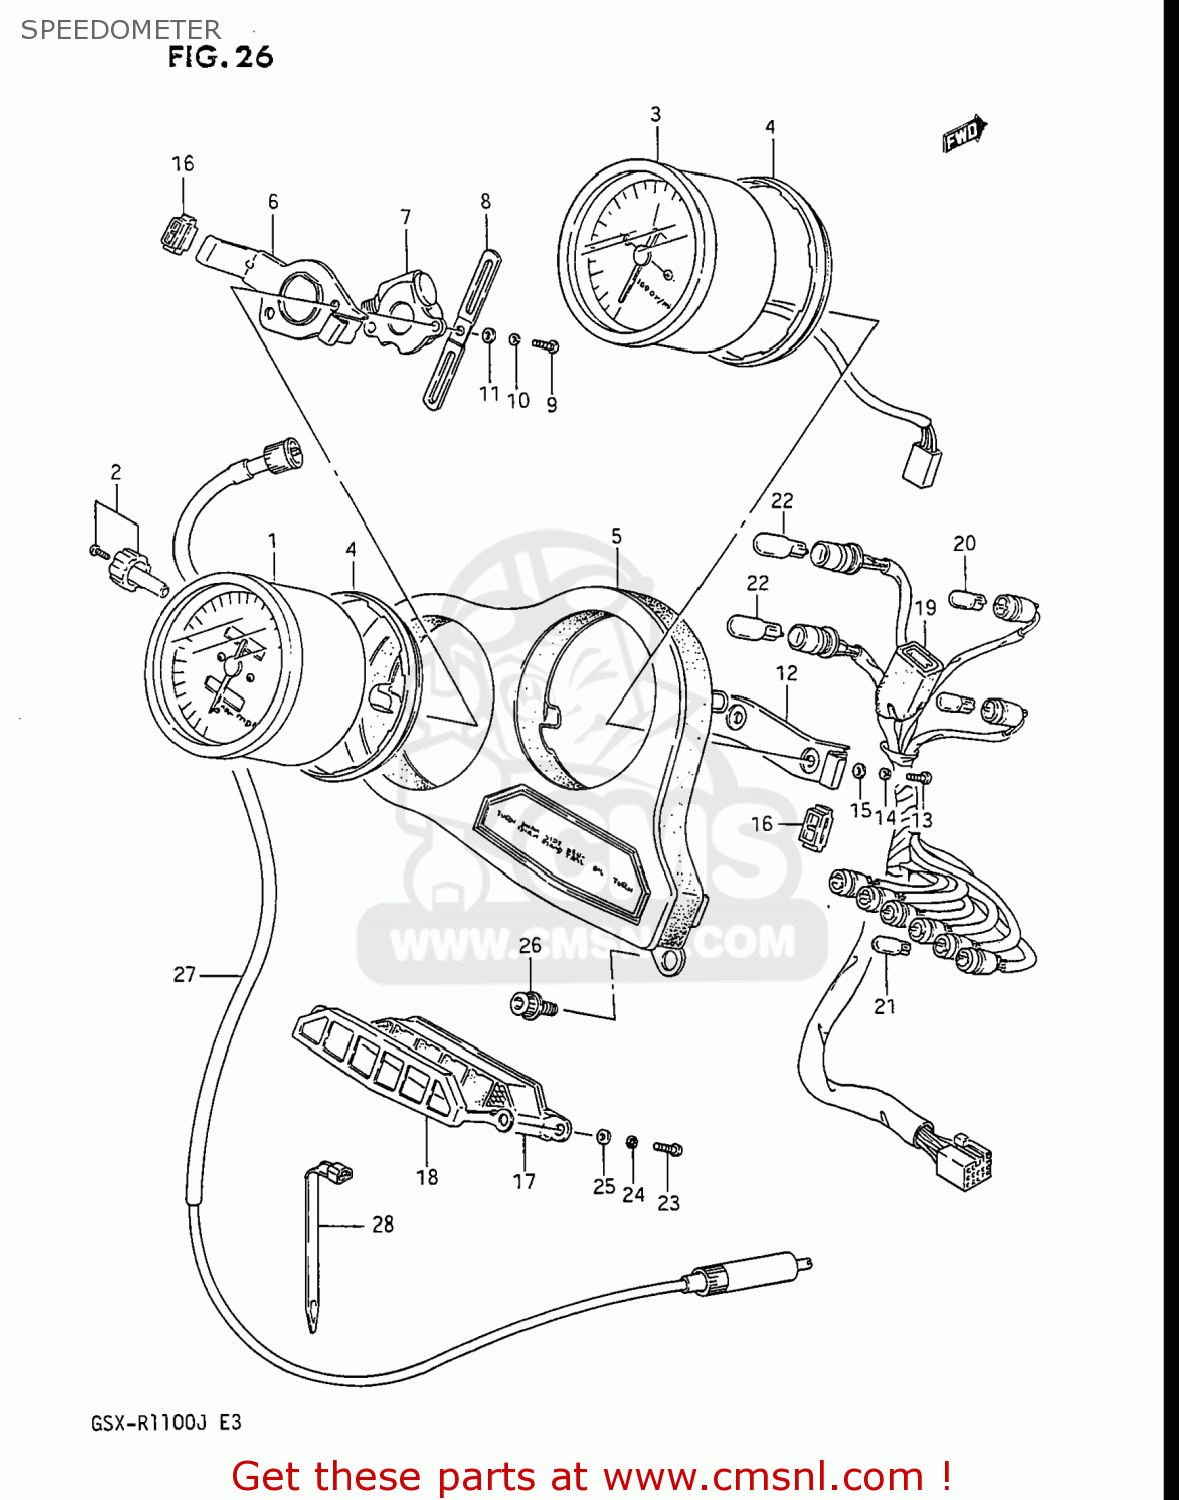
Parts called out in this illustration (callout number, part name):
1	SPEEDOMETER ASSEMBLY
2	KNOB,TRIP
3	TACHOMETER
4	CUSHION
5	BRACKET,METER
6	PLATE,SPEEDOMETER
7	BOX,GEAR
8	CLAMP
9	SCREW
10	LOCK WASHER
11	WASHER
12	PLATE,TACHOMETER
13	SCREW
14	LOCK WASHER
15	WASHER
16	CUSHION
17	BOX,PILOT LAMP
18	PLATE,PILOT LAMP
19	SOCKET,METER
20	BULB(12V3W,T6.5)
21	BULB(12V1.7W,T6.5)
22	BULB(12V3.4W,T10)
23	SCREW
24	LOCK WASHER
25	WASHER
26	BOLT
27	CABLE ASSY,SPEEDOMETER
28	CLAMP(L:125)
